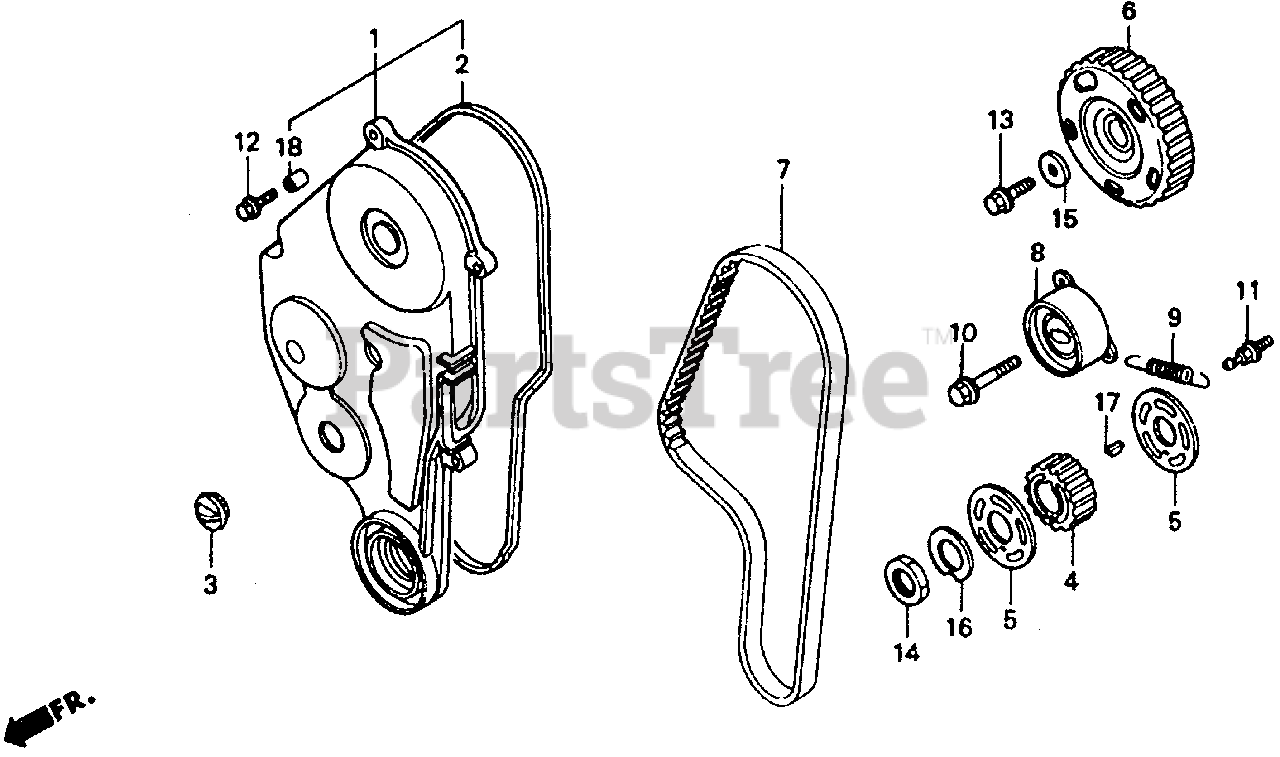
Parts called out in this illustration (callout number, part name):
1	COVER, TIMING BELT
2	GASKET, TIMING BELT COVER
3	GROMMET, TIMING BELT COVER
4	PULLEY, TIMING BELT DRIVE
5	PLATE, TIMING BELT GUIDE
6	PULLEY, TIMING BELT DRIVEN
7	BELT, TIMING
8	TENSIONER, TIMING BELT
9	SPRING, TIMING BELT ADJUSTING
10	BOLT A, TENSIONER
11	BOLT, TIMING BELT ADJUSTER (Honda Code 2644961). SPRING (NAGOYA RASHI)
12	BOLT, FLANGE (6X20) (CT200)
13	BOLT, FLANGE (8X22)
14	NUT, LOCK (27MM)
15	WASHER, SPECIAL (28X8.5X4.0)
16	WASHER, LOCK (6MM)
17	KEY, SPECIAL (16X15)
18	COLLAR, CONTROL LEVER
